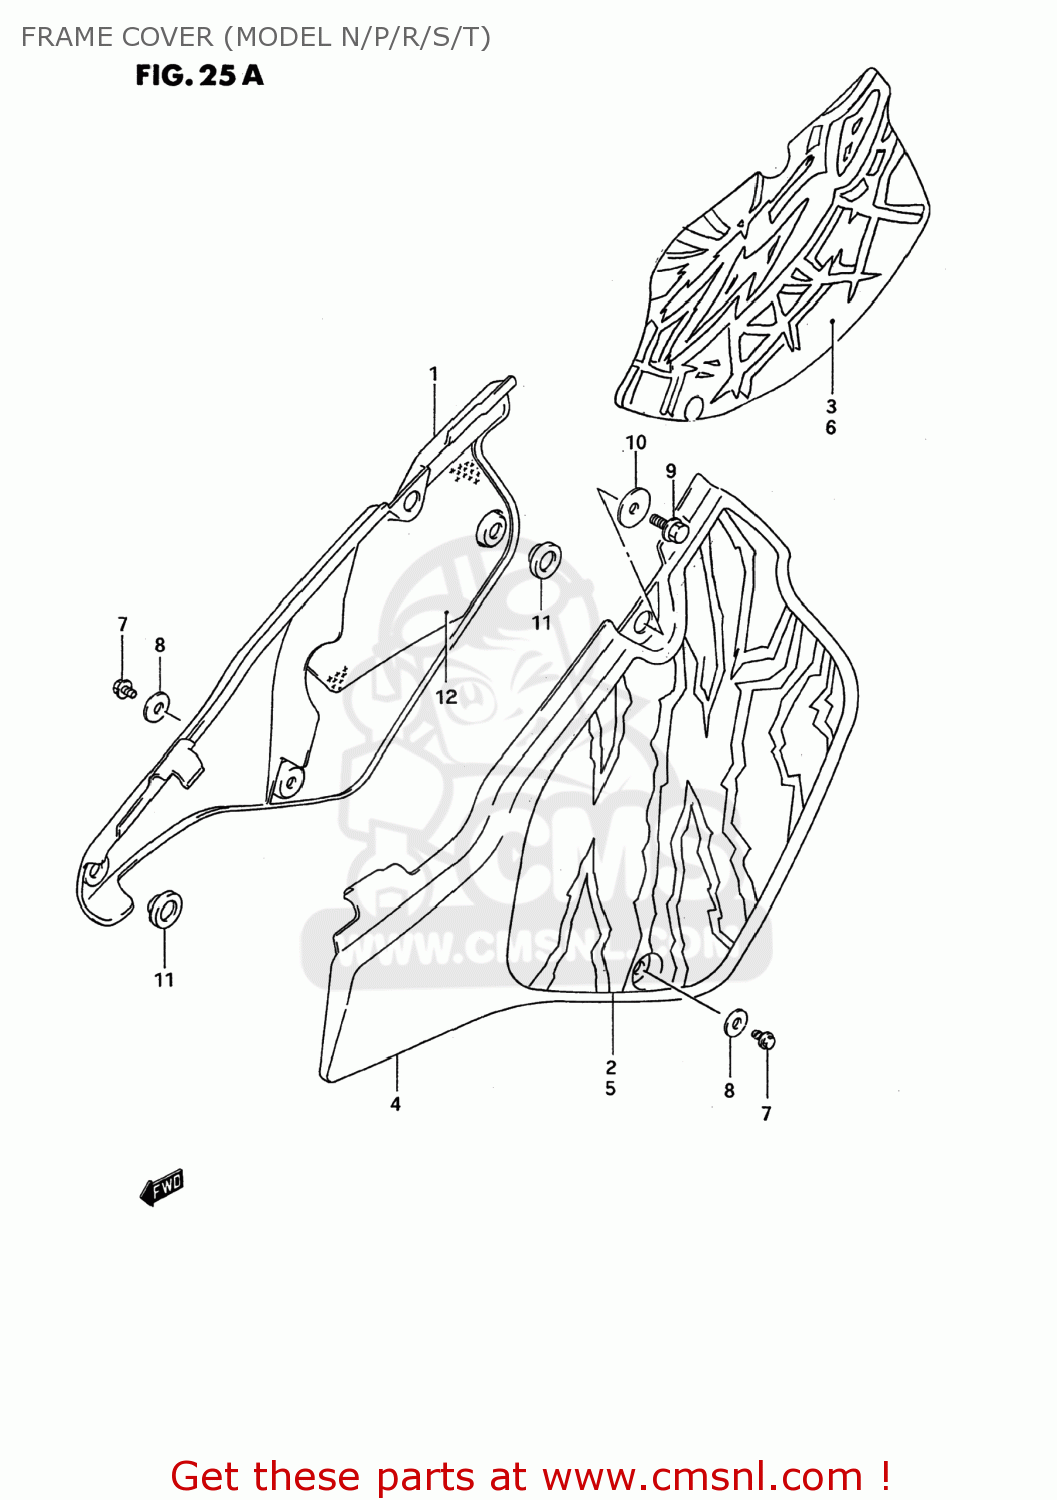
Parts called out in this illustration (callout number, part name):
1	COVER,FRAME,R(WHITE)
2	TAPE,FRAME COVER,RIGHT
3	EMBLEM,FRAME COVER,RIGHT
4	COVER,FRAME,L(WHITE)
5	TAPE,FRAME COVER,LEFT
6	EMBLEM,FRAME COVER,LEFT
7	BOLT
8	GASKET(6.5X20X1.5) (NAS)
9	BOLT
10	WASHER
11	CUSHION
12	HEATSHIELD,FRAME COVER,R
